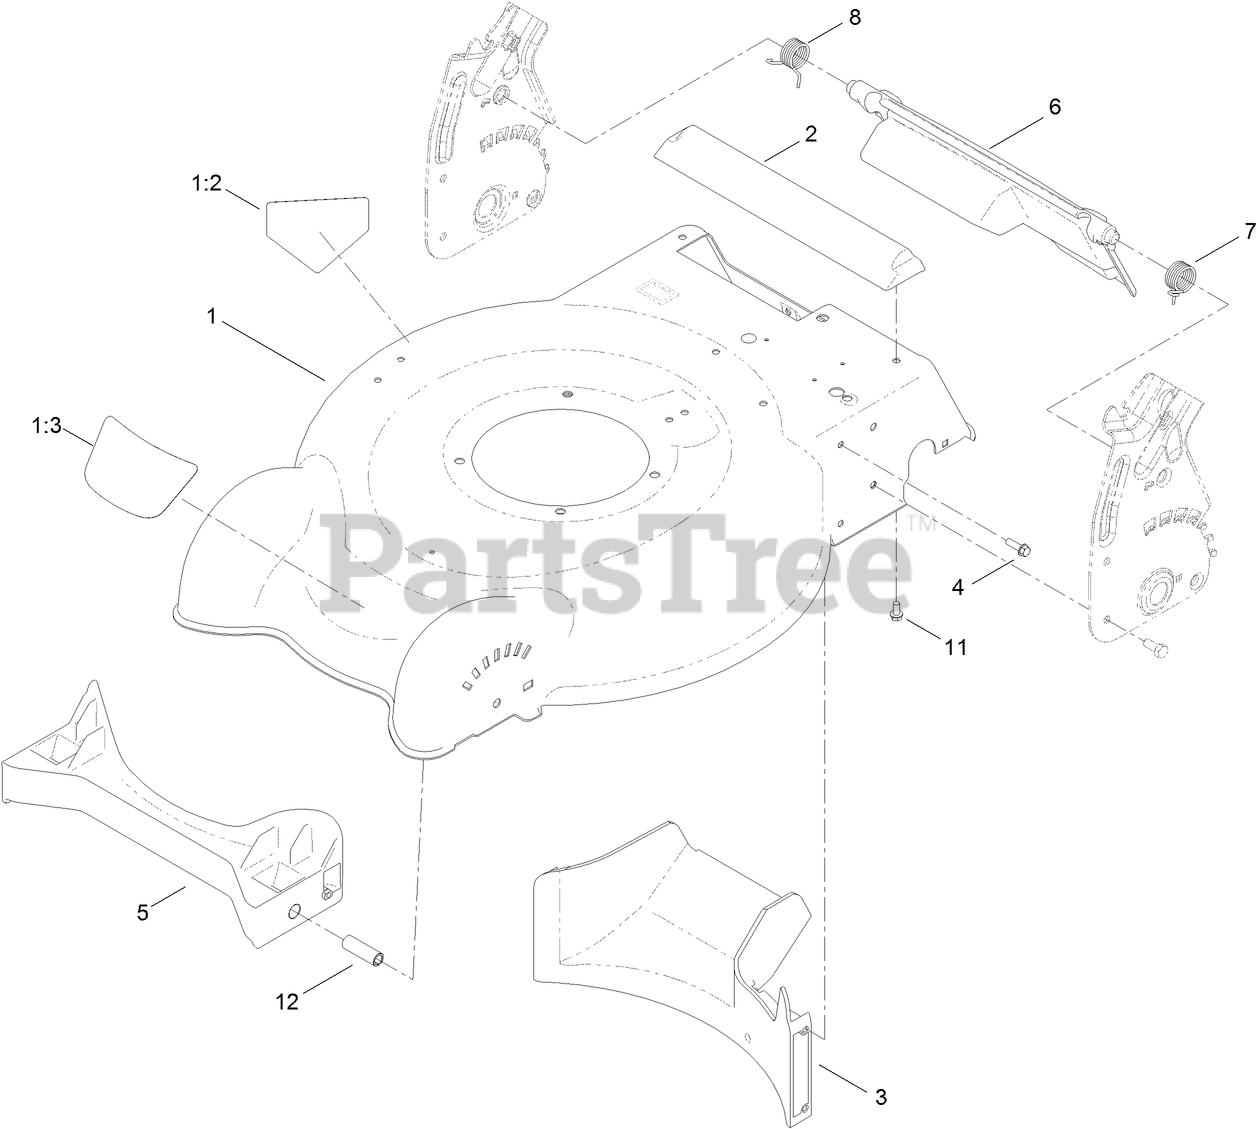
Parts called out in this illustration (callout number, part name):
1	HOUSING ASM
1:2	DECAL-DANGER
1:3	Decal-Deck
2	CHUTE-REAR
3	BAFFLE-REAR
4	SCREW-HWH
5	BAFFLE-FRONT
6	Rear Deflector ASM
7	SPRING-TORSION, LH
8	SPRING-TORSION, RH
11	SCREW-PLASTITE
12	SPACER-BAFFLE, FRONT
